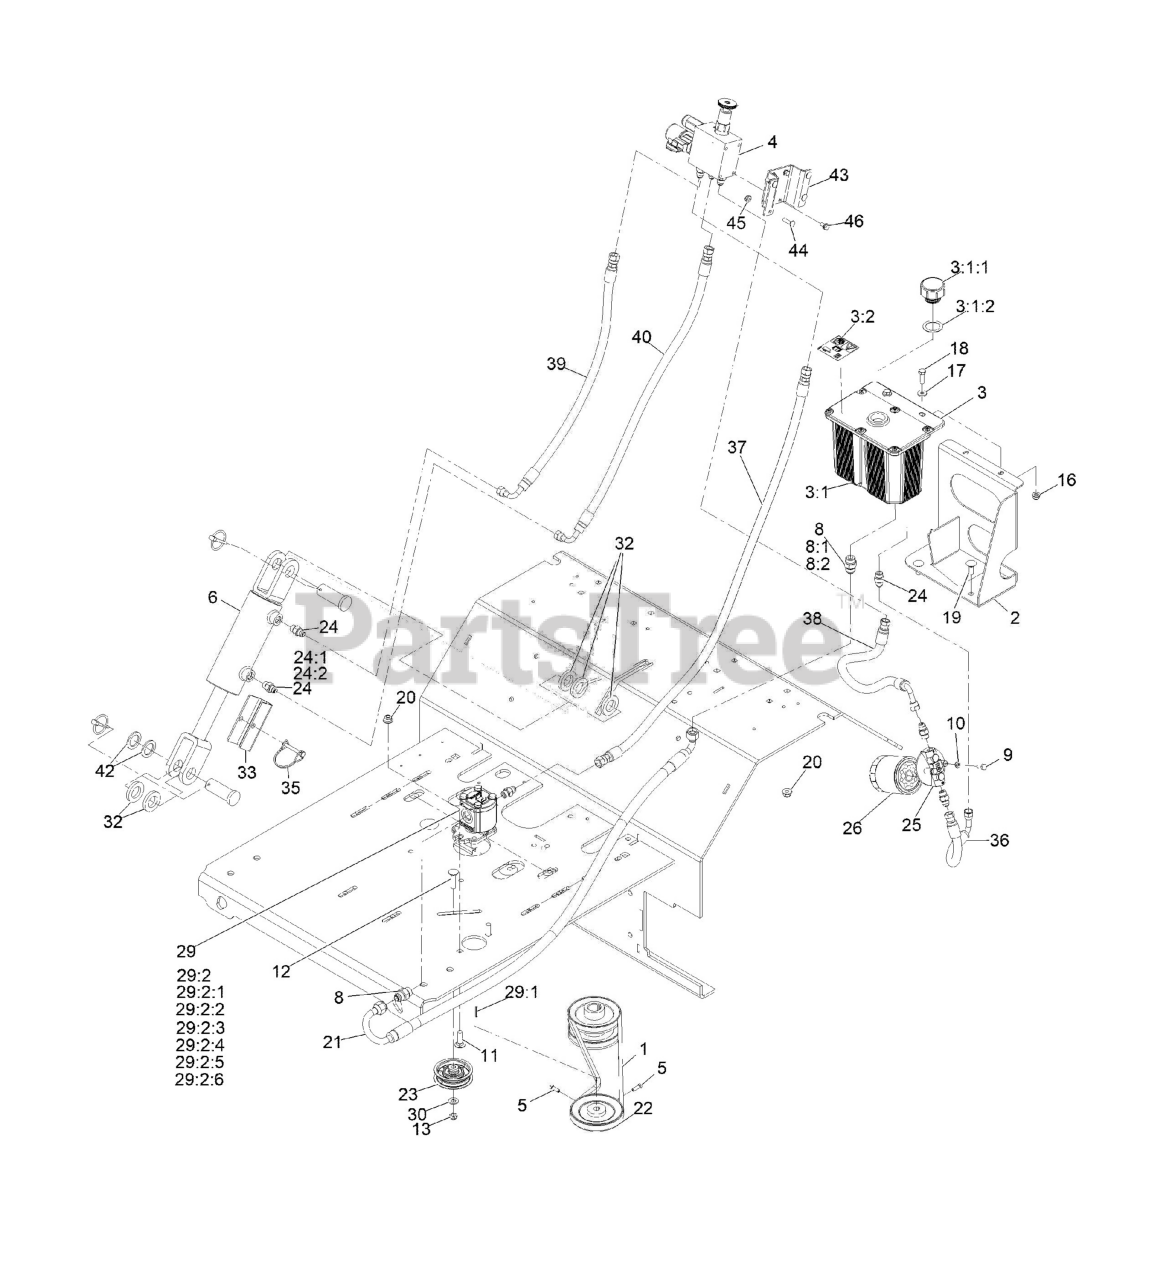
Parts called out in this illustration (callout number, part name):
1	BELT-4L SECTION
2	BRACKET-TANK, HYDRAULIC
3	RESERVOIR ASM
3:1	Tank-Hydraulic
3:1:1	Cap-Reservoir, HYD
3:1:2	GASKET-CAP
3:2	DECAL-WARNING
4	Manifold ASM
5	SCREW-SQH
6	HYD CYLINDER ASM
8	FITTING-STRAIGHT
9	SCREW-HH
10	WASHER-LOCK
11	BOLT-CARR
12	SCREW-CARR
16	NUT-HF, NI
17	WASHER-FLAT
18	SCREW-HH
19	BOLT-CARR
20	NUT-HF, NI
21	HOSE-HYDRAULIC
23	PULLEY-IDLER, FLAT
24	FITTING-STRAIGHT
24:1	BOSS O-RING
25	HEAD-FILTER
26	FILTER-25 MICRON, BI-DIRECTIONAL
29	HYDRAULIC PUMP ASM
29:1	KEY-SQUARE
29:2	SEAL KIT
29:2:1	Seal-Anti Extrusion
29:2:2	Seal-Anti Extrusion
29:2:3	Seal-Shaft
29:2:4	Seal-Upper
29:2:5	Seal
29:2:6	O-Ring
30	WASHER-FLAT
33	STOP-CYLINDER
35	PIN-HITCH
36	HOSE-HYDRAULIC, LP
37	HOSE-HYDRAULIC
38	HOSE-HYDRAULIC
39	HOSE-HYDRAULIC
40	Hydraulic Hose ASM
42	WASHER-THRUST
43	Bracket-Sensor, Control (Depth)
44	SCREW-CARR
46	SCREW-HWH
